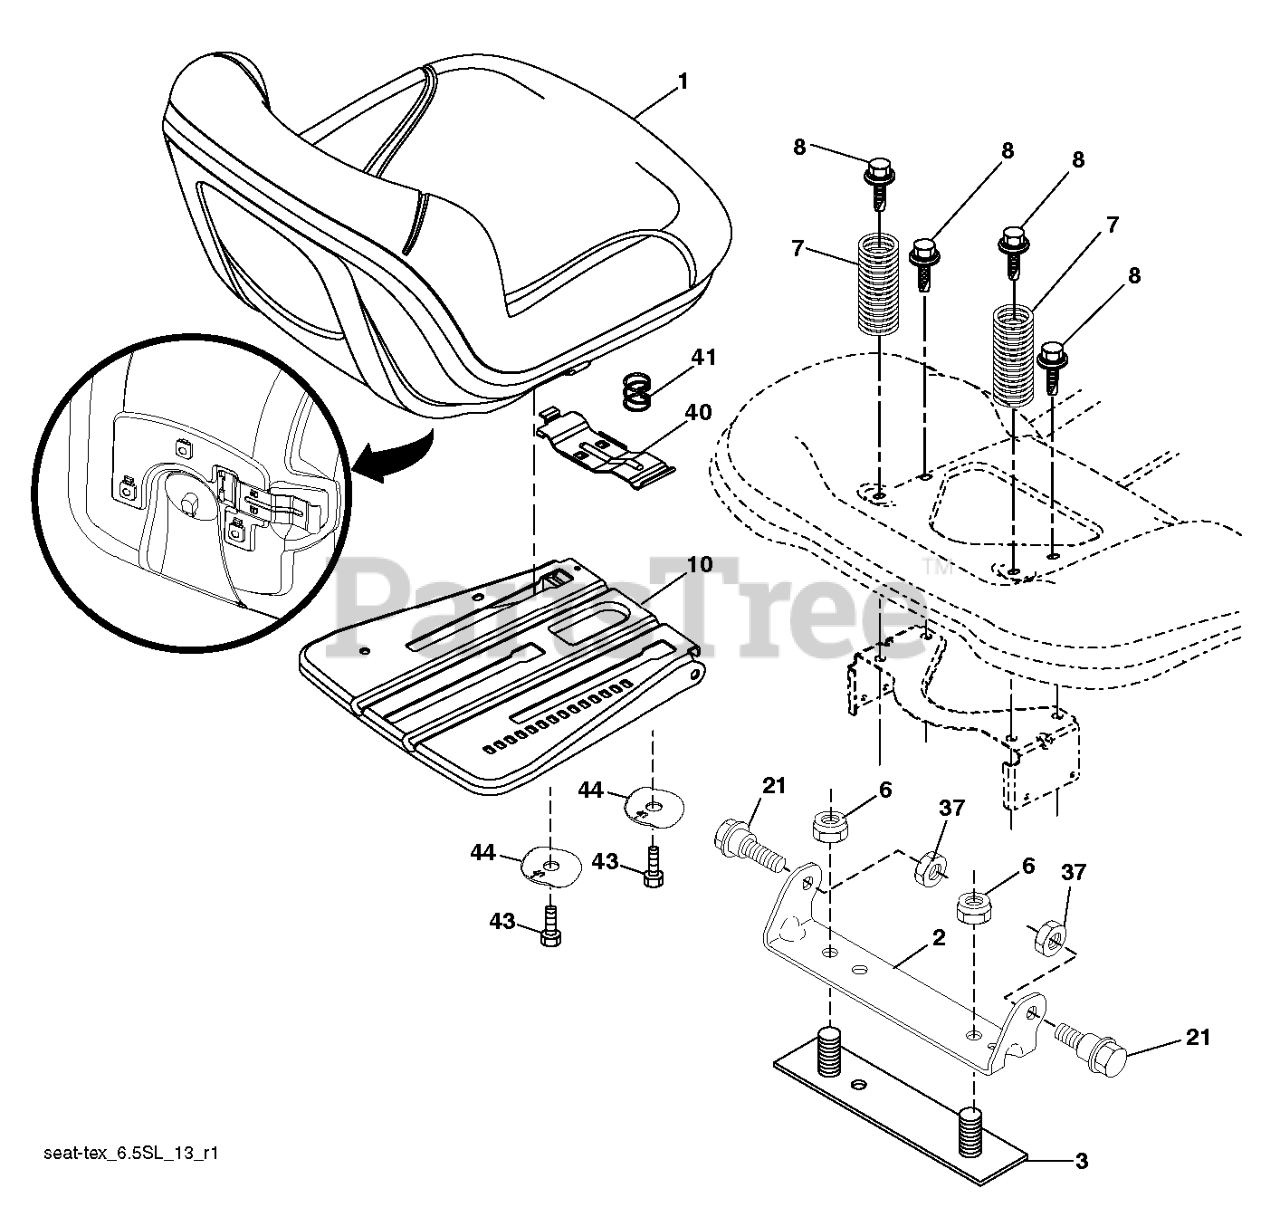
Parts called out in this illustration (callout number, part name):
1	SEAT.TH150.MS498.GRY.HUSQ.TEX
2	BRKT.PIVOT.FENDER
3	STRAP
6	NUT
7	SPRING.COMPRESS.SEAT.TAPERED
8	BOLT.5/16-18UNCX3/4 W/SEMS.BLK
10	PLATE.PNT.SEAT.SLIDE.3PT.EDIP
21	BOLT.5/16-18X5/8.SHOULDER
37	NUT.71038.31-18.HEX.NYLOCK
40	HANDLE.SLIDE.SEAT.TEX.BLACK
41	SPRING.LATCH.SEAT.TEX
44	WASHER.WINGED.3/8ID.1.5OD
